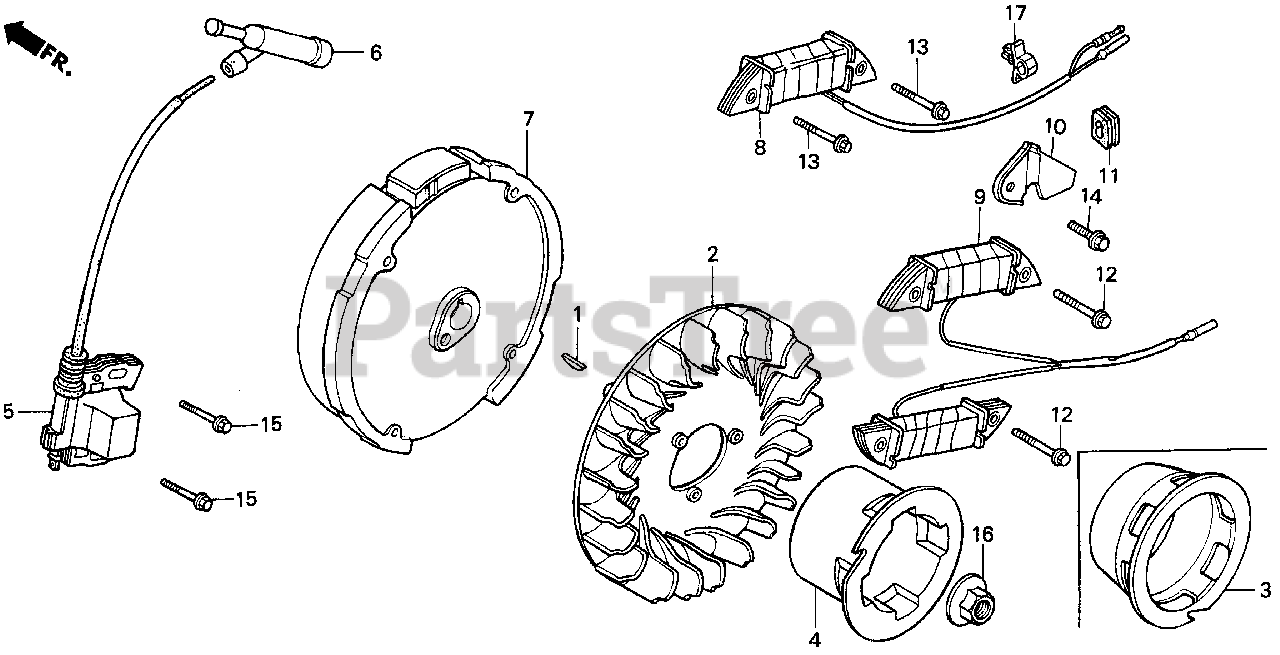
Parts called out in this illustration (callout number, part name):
1	KEY, SPECIAL WOODRUFF (25X18)
2	FAN, COOLING
3	PULLEY, STARTER
4	PULLEY, STARTER
5	COIL ASSY., IGNITION
6	CAP ASSY., NOISE SUPPRESSOR (NICHIWA Y-EZ RTFM256)
7	FLYWHEEL (LAMP)
8	COIL ASSY., LAMP (12V/15W)
10	CLAMP, WIRE
11	GROMMET, WIRE
13	BOLT, FLANGE (6X23) (CT200)
14	BOLT, FLANGE (5X10)
15	BOLT, FLANGE (6X25) (CT200)
16	NUT, SPECIAL (14MM)
17	CLIP, CABLE (6MM) (WHITE)
